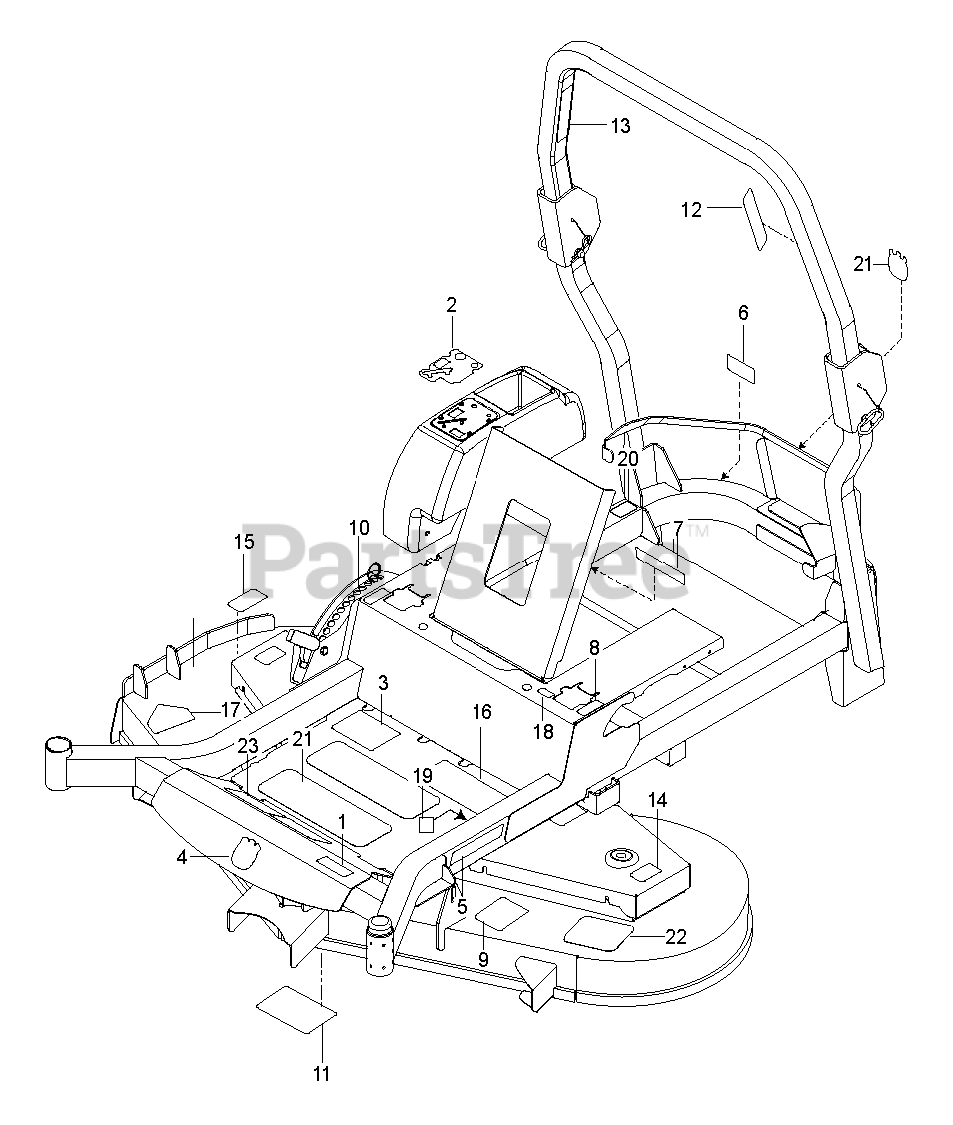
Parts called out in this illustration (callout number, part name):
1	DECAL ZTR MZT61 HUSQVARNA
2	DECAL, CONSOLE HUS
3	DECAL.ZTR.STRTNGINST.REMOTECHK
4	DECAL.AUGER.HUSQ.CROWN.SNOW
5	RP.DECAL.BADGE.170MM.TEXTLOGO
6	DECAL, BELT DRIVE
7	EURO DECAL-BATTERY WARNIN6
8	DECAL.ZTR.MOTCONTRL.SYMBOL.HUS
9	DECAL, BELT ROUTING
10	DECAL, HEIGHT ADJUST
11	DECAL, SERVICE
12	DECAL, ROPS, WARNING
13	DECAL ROPS
14	DECAL.DECK.6MIL.EURO.NOSTEP
15	DECAL.DECK.6MIL./DEF.SHLD.WARN
16	DECAL.ZTR.WARNING.SMARTIGNITIN
17	DECAL, DECK DEFLECTOR, WARNING
18	DECAL.STR.S.T.SYSMBOLONLY.2014
19	DECAL.80.DBA.AUSTRALIA
20	DECAL ROPS
21	DECAL, CROWN H, 110MM
22	ANTI-SKID PAD
23	FOOT PAD
